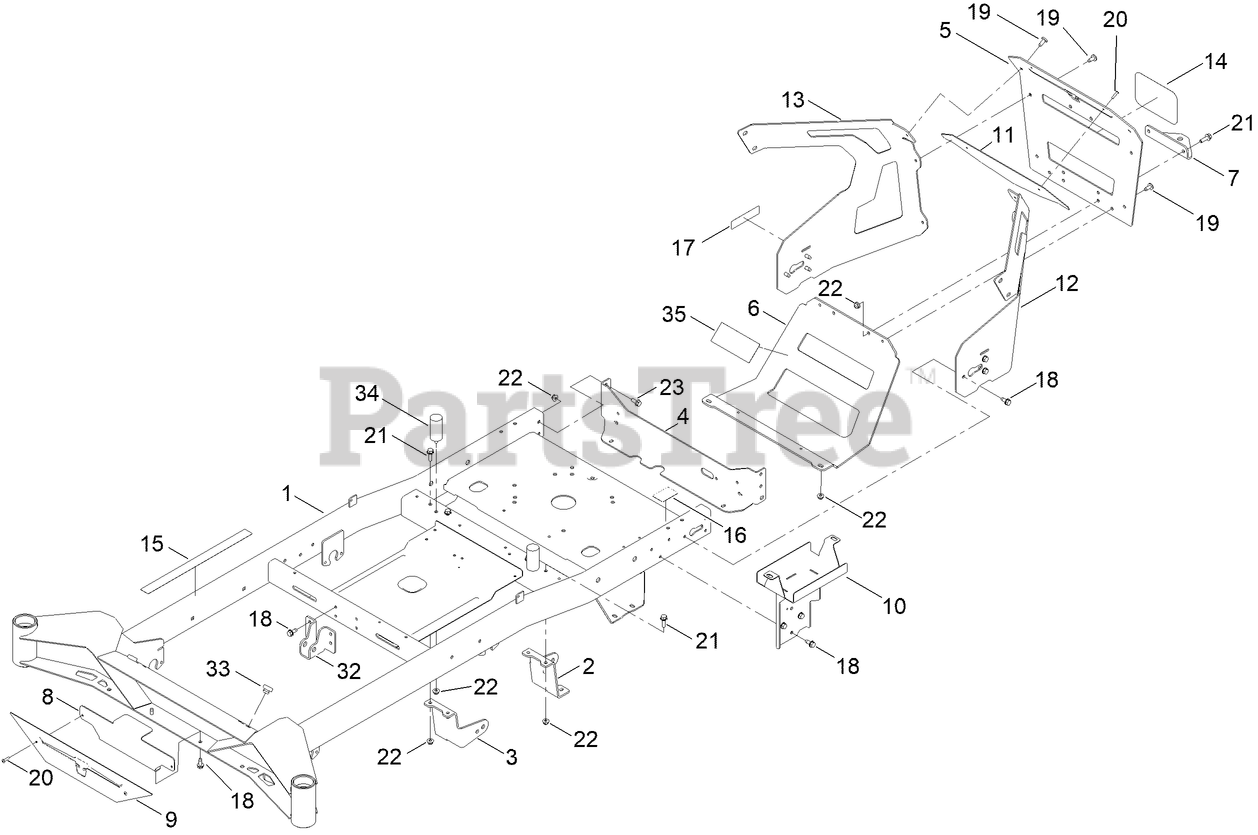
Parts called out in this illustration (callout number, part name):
1	SERVICE ASM-FRAME, TITAN
2	MOUNT-DRIVE, LH
3	MOUNT-DRIVE, RH
4	PLATE-MOUNT, REAR
5	GUARD-ENGINE
6	GUARD-MUFFLER
7	BRACKET-HITCH
8	PLATE-BACKER
9	LOGO-PLATE-FRONT
10	WA-BATTERY MOUNT
11	PLATE-BACKER
12	GUARD-ENGINE LH
13	GUARD-ENGINE-RH
14	DECAL
15	DECAL-WARNING
16	DECAL-BYPASS
17	DECAL-SPARK ARRESTER
18	SCREW-HWHTF
20	RIVET-TRIFOLD
21	SCREW-HHF
22	NUT-HF
23	SCREW-HHF
32	BRACKET-MOUNT DAMPER, LOWER
33	BUMPER-RUBBER
34	BUMPER-RUBBER
35	TAPE-HEAT
